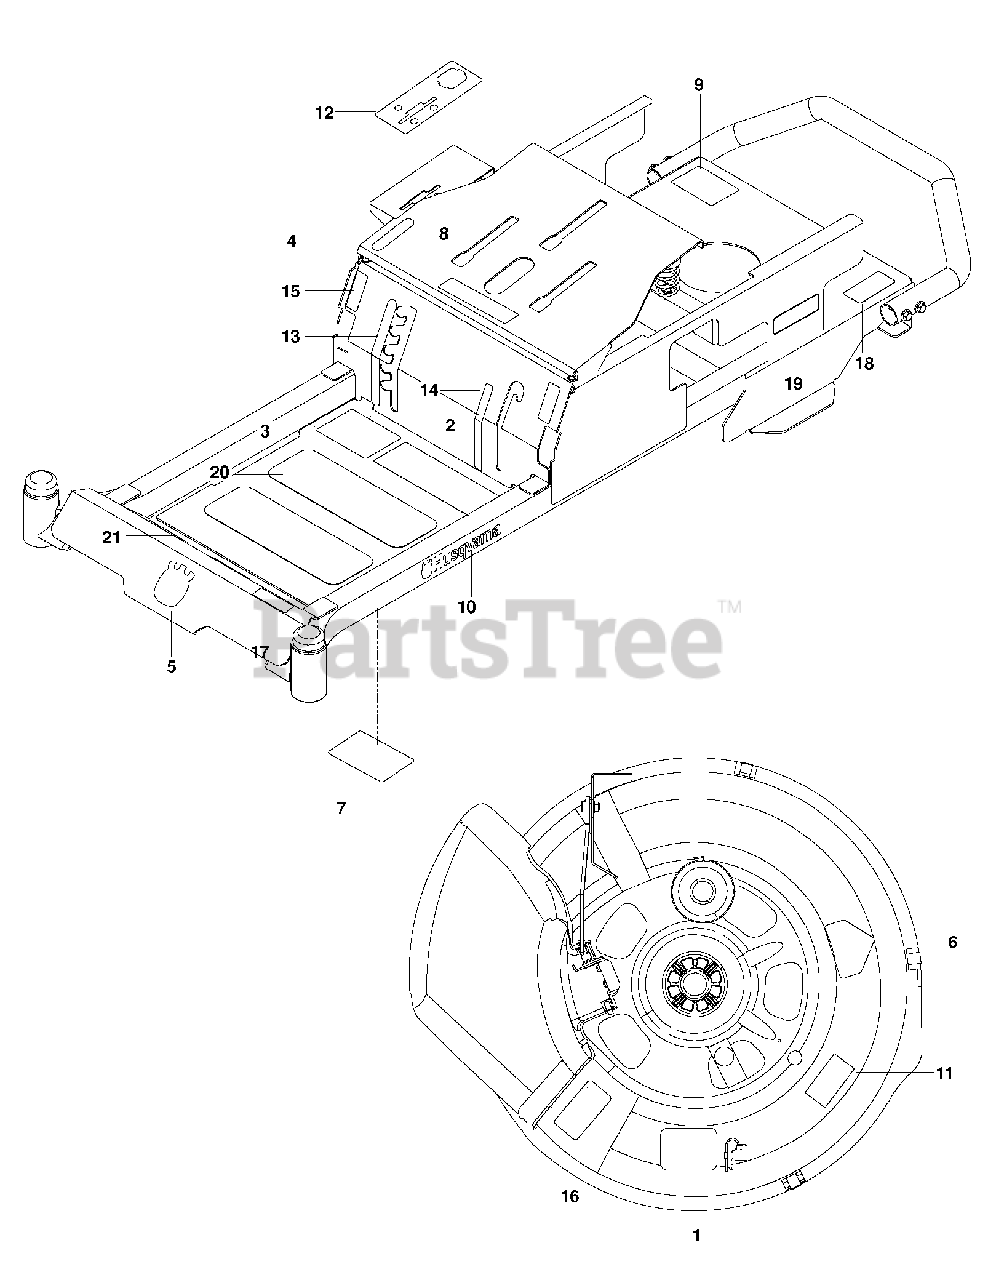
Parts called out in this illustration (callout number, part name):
1	DECAL, BELT ROUTING
2	DECAL, SAFETY WARNING
3	DECAL, WARNING
4	DECAL, PARK BRAKE
5	DECAL.AUGER.HUSQ.CROWN.SNOW
6	DECAL, CPSC
7	DECAL, SERVICE
8	EURO DECAL-BATTERY WARNIN6
9	DECAL, DO NOT TOW
10	RP.DECAL.BADGE.170MM.TEXTLOGO
11	DECAL, EURO SEVERING
12	DECAL.ZTR.CONTROL.PANEL
13	DECAL, DECK HEIGHT
14	DECAL, BLADE ENGAGEMENT
15	DECAL, MOTION CONTROL
16	DECAL.DECK.6MIL./DEF.SHLD.WARN
17	DECAL, RZ3016
18	DECAL, PROP. 65
19	DECAL, WARNING SPARK ARRESTOR
20	ANTI-SKID PAD
